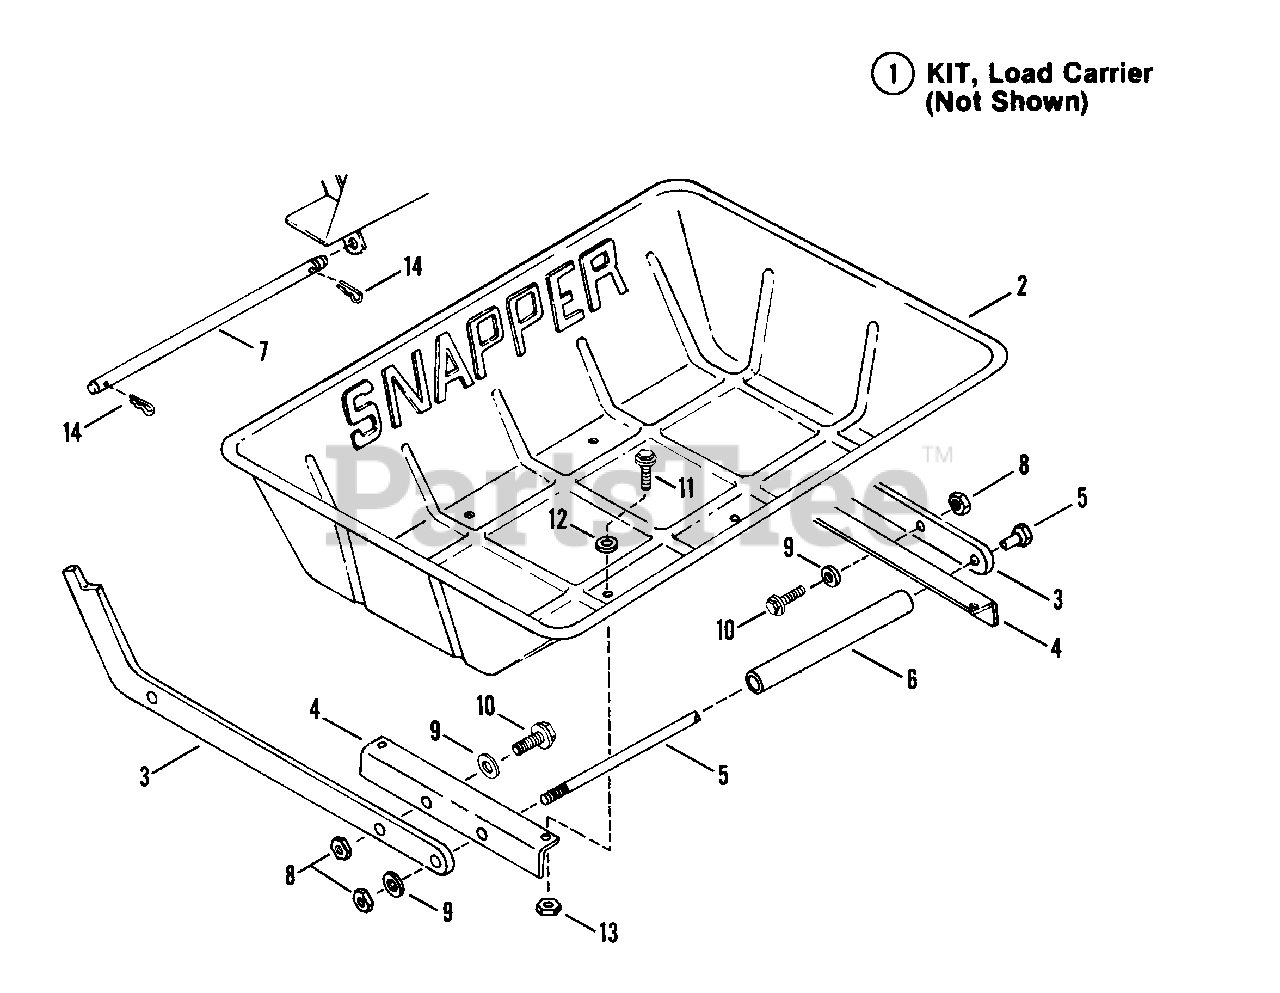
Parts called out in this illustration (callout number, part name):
2	BOX, Tote
3	RAIL, Side
5	BOLT, 3/8-16x10", Tote Box
6	SPACER, Box
7	PIN
8	LOCKNUT, 3/8-16 Hex
9	WASHER, 3/8 SAE
10	CAPSCREW, 3/8-16x1", Hex Head
11	CAPSCREW, 1/4-28x3/4" Grade 5, Hex Head
12	WASHER, 1/4 SAE
13	LOCKNUT, 1/4-28, Hex
14	PIN, Hair
